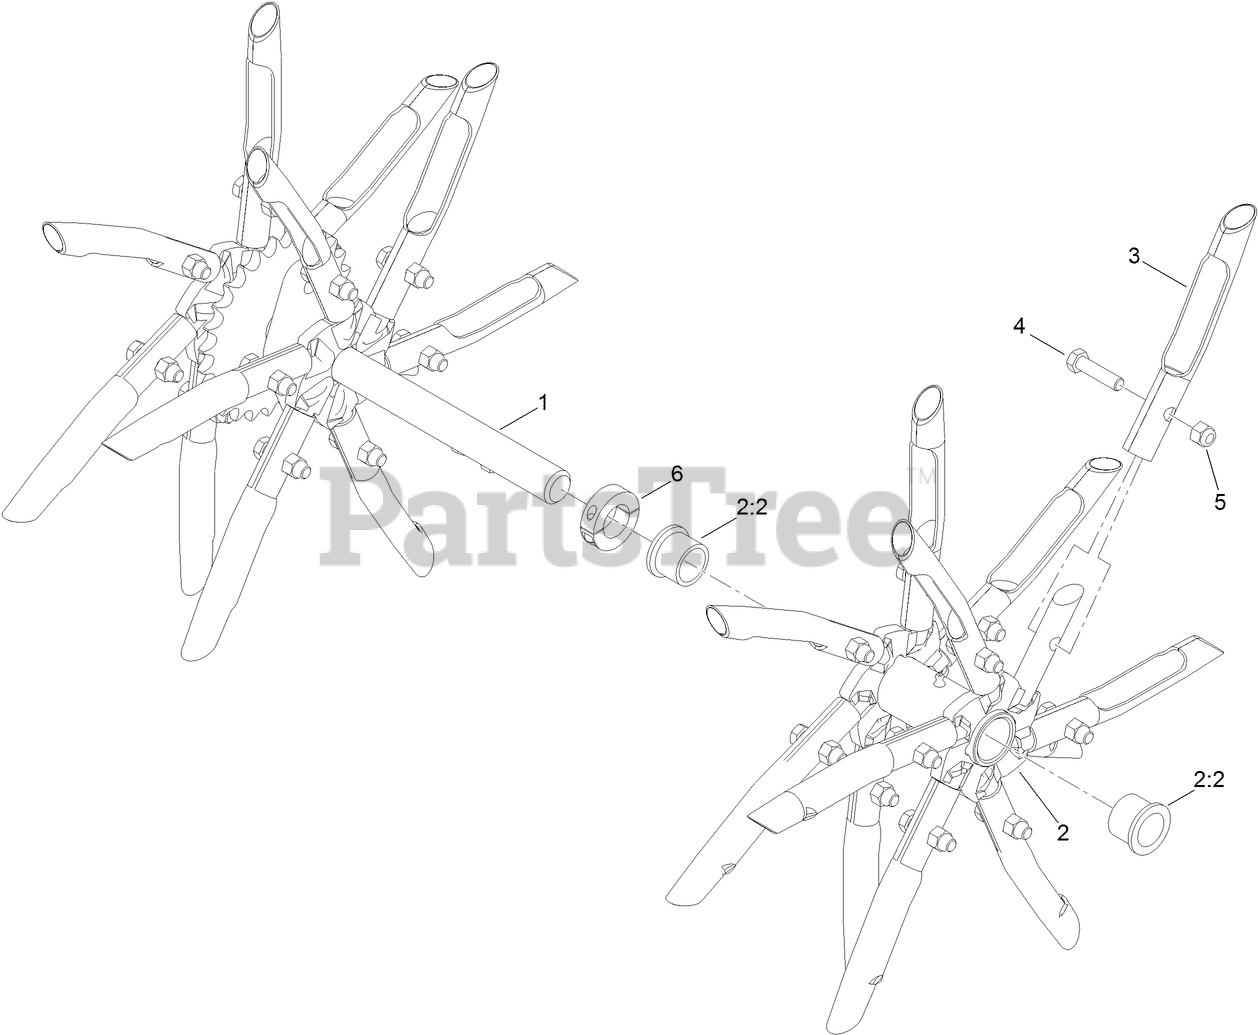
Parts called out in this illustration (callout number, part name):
1	SHAFT-TINE, RH
2	FLOAT TINE SHAFT ASM
2:2	BUSHING-FLANGE
3	TINE-CORING (3/4 INCH)
4	SCREW-HH
5	NUT-LOCK, NI
6	COLLAR-LOCKING
